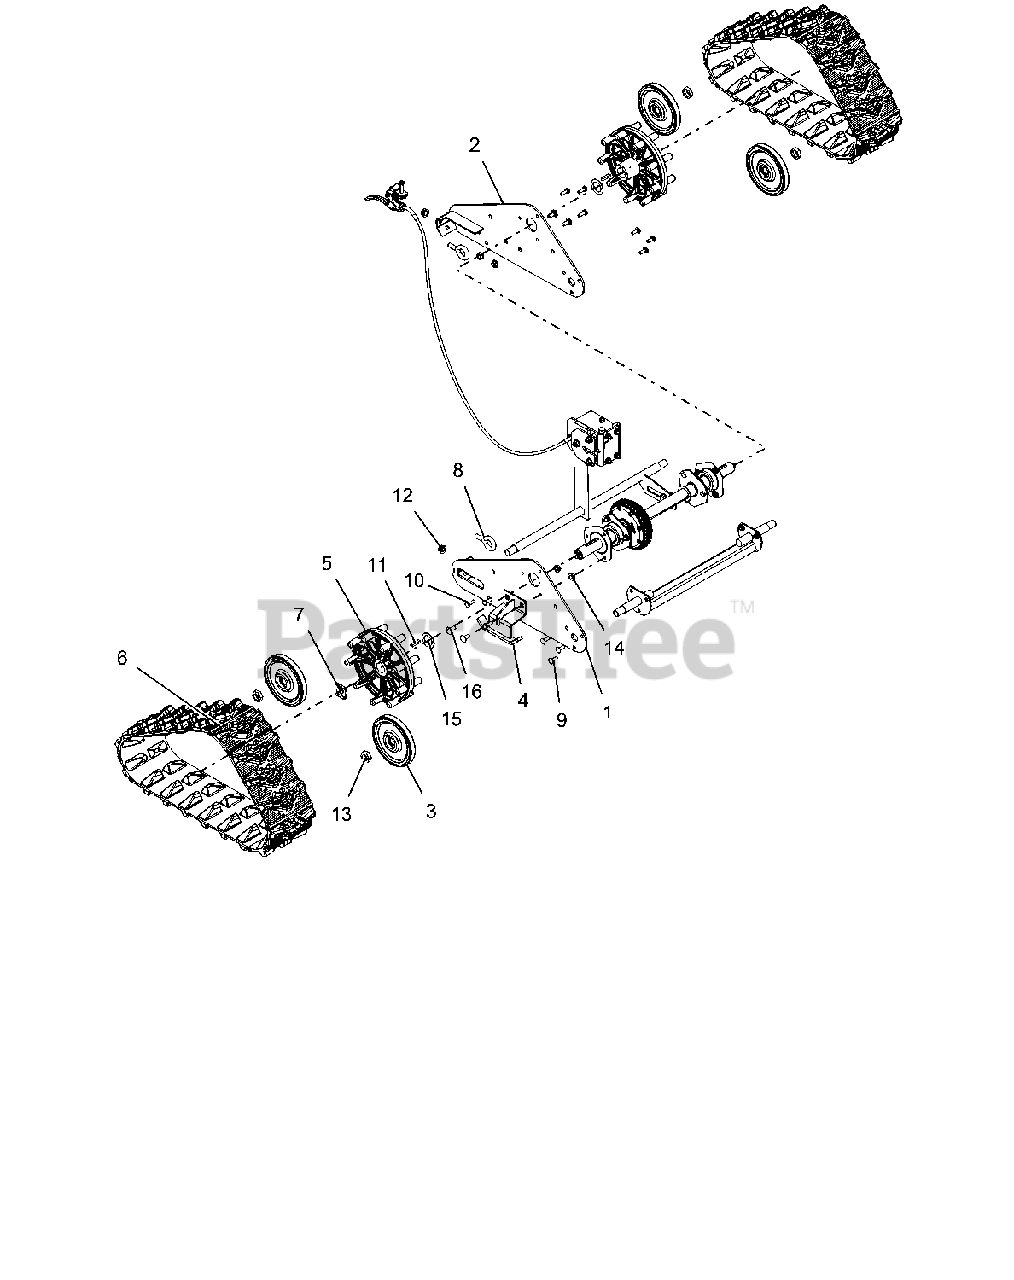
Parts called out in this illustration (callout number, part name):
1	SIDE PLATE, RH-DELUXE TRACK
2	SIDE PLATE, LH-DELUXE TRACK
3	WHEEL, BOGIE - SINGLE BEARING
4	RUNNER, GUIDE-TRACK
5	WHEEL, MACHINED DRIVE
6	TRACK, RUBBER
7	CLIP, SNAP .625 DIA
8	BLT-EYE .375-16X.880 YWZC
9	@BLT-RDHDSQNK .25-20X.75 G5YZ
10	@BLT-HEX .25-20X.75 GR5 YWZC
11	KEY-RECT .25X.188X1.00
12	NUT-LK-CTR-FLG .38-16 YWZC
13	@NUT-LK-NYL .625-18 YWZC
14	@NUT-LK-TOP-FLG .31-18 YWZC
15	WSHR-FL-STL 1.010X1.505X.062YZ
16	@BLT-RDHDSQNK .31-18X.75 G5YZ
